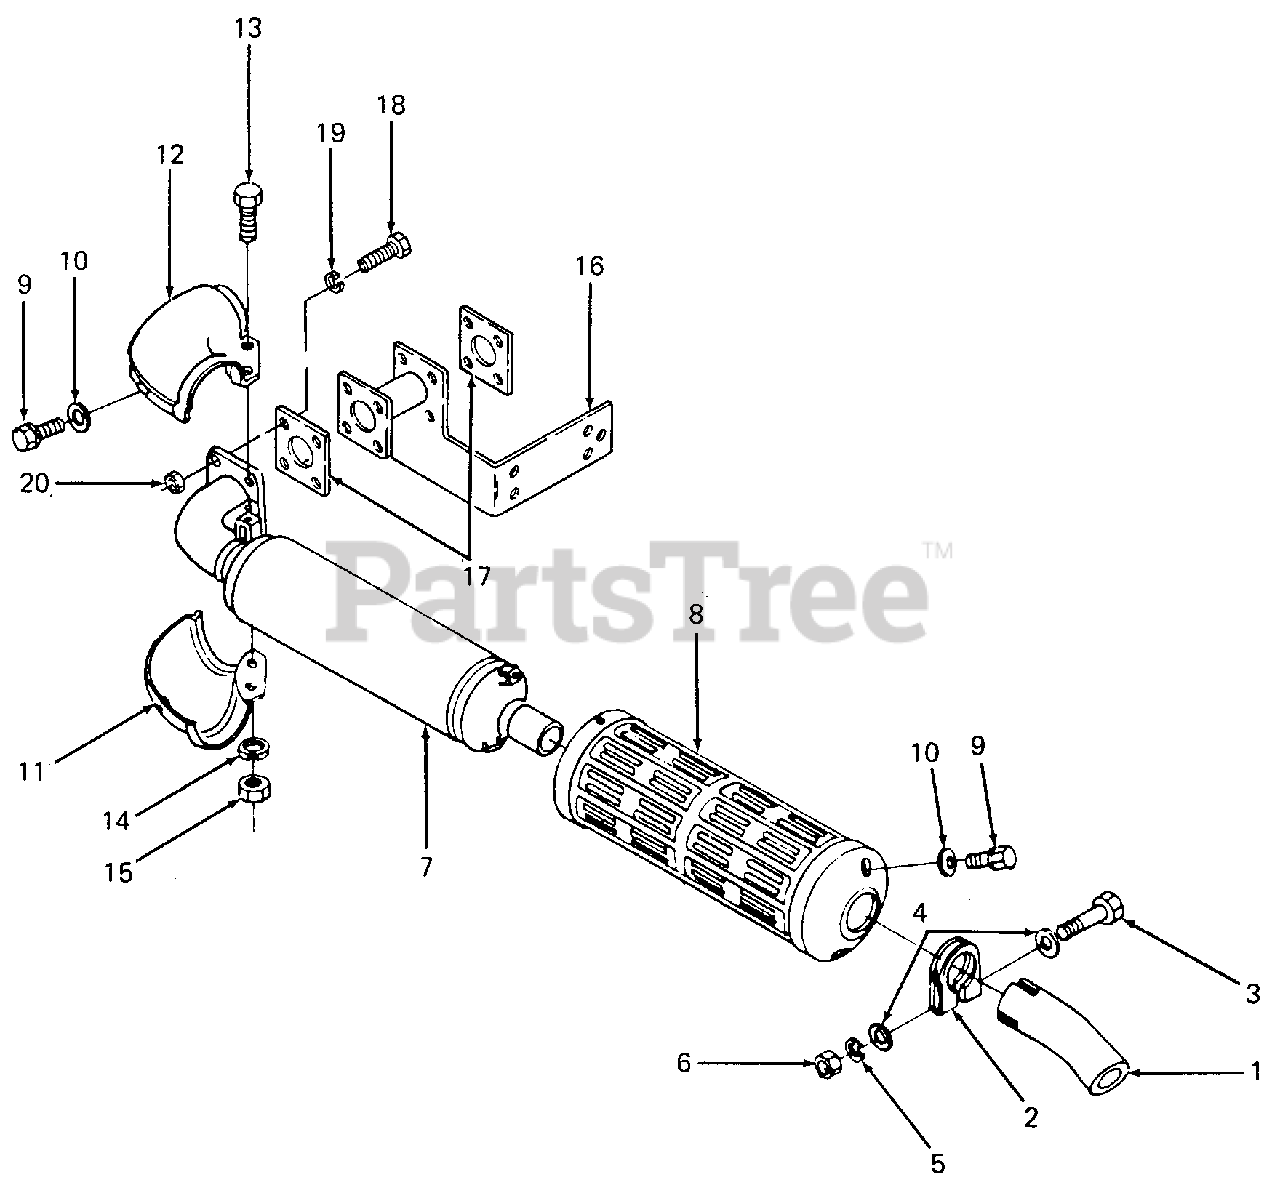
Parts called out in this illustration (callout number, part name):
1	Pipe, Muffler
3	Screw, Hex Cap
5	Washer, Spring
8	Cover, Muffler w/Graphic
9	Screw, Hex Cap
10	Washer, Flat
11	Cover, Muffler Flange - LH
12	Cover w/Nut, Muffler Flange - RH
13	Screw, Hex Cap
14	Washer, Spring
16	Extension, Exhaust Manifold
17	Gasket, Muffler
18	Screw, Hex Cap, 5/16-24 X 1.0 Lg GR5
19	Washer, Lock, 5/16
20	Nut, Hex, 5/16-24 GR5
